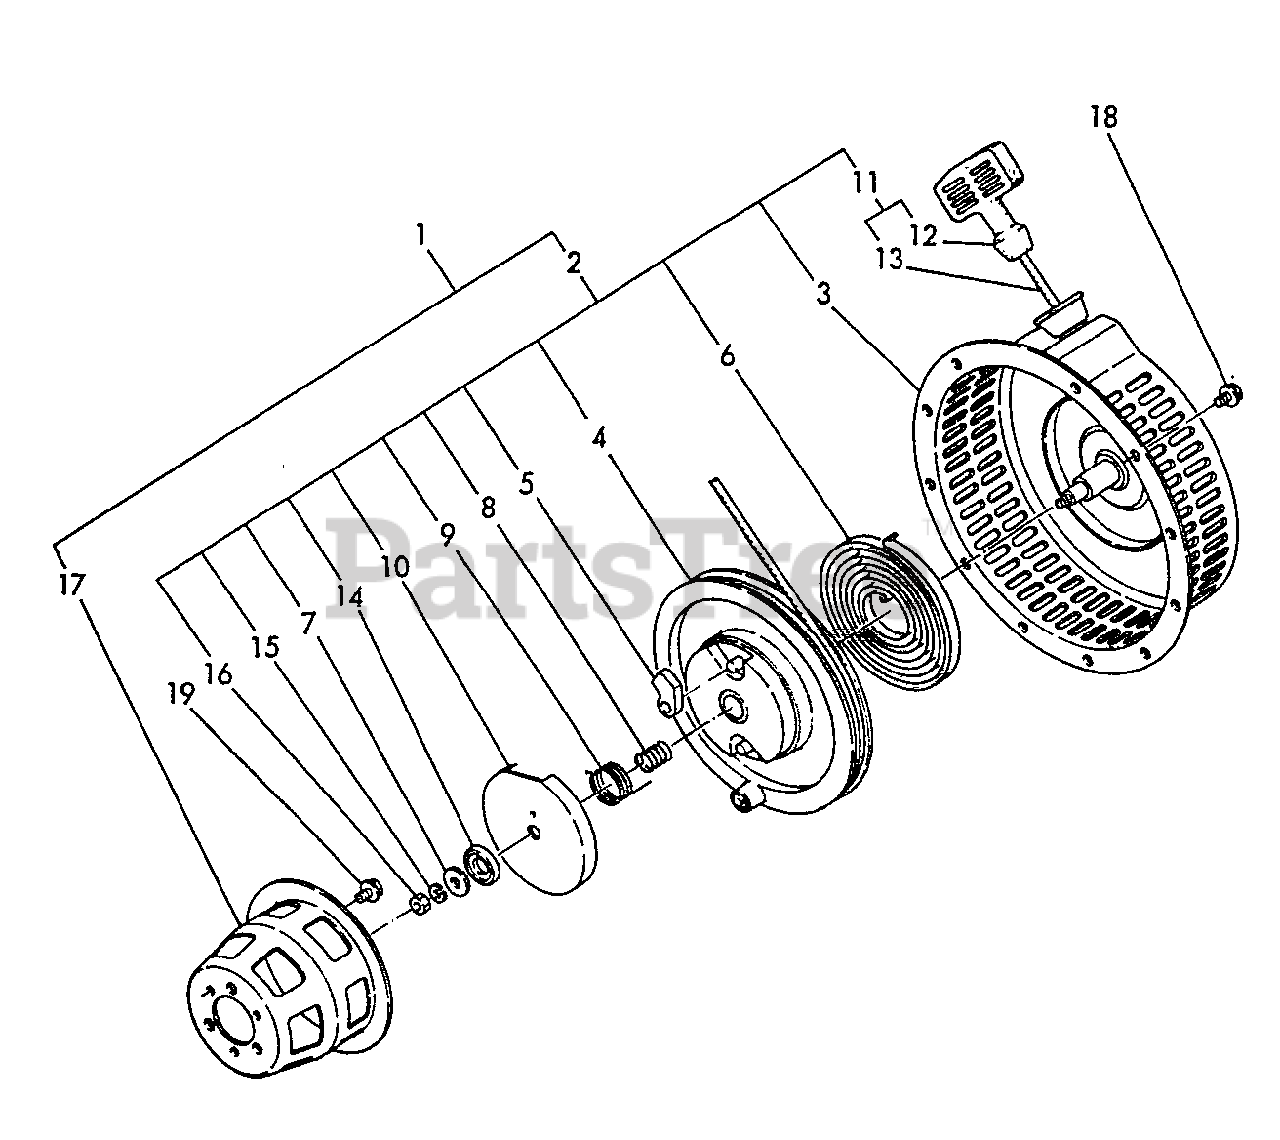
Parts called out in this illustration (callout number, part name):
1	STARTER ASSY
2	STARTER ASSY
3	CASE, STARTER
5	RATCHET
6	SPRING
7	WASHER, THRUST
8	SPRING, FRICTION
9	SPRING, RETURN
10	PLATE, FRICTION
11	STARTER ROPE ASSY
12	KNOB, STARTER
13	ROPE, STARTER
14	WASHER, THRUST
15	LOCKWASHER - 6
17	REEL, ROPE
18	BOLT - 6X8 -- PLATED
19	BOLT - 6X12 -- PLATED
